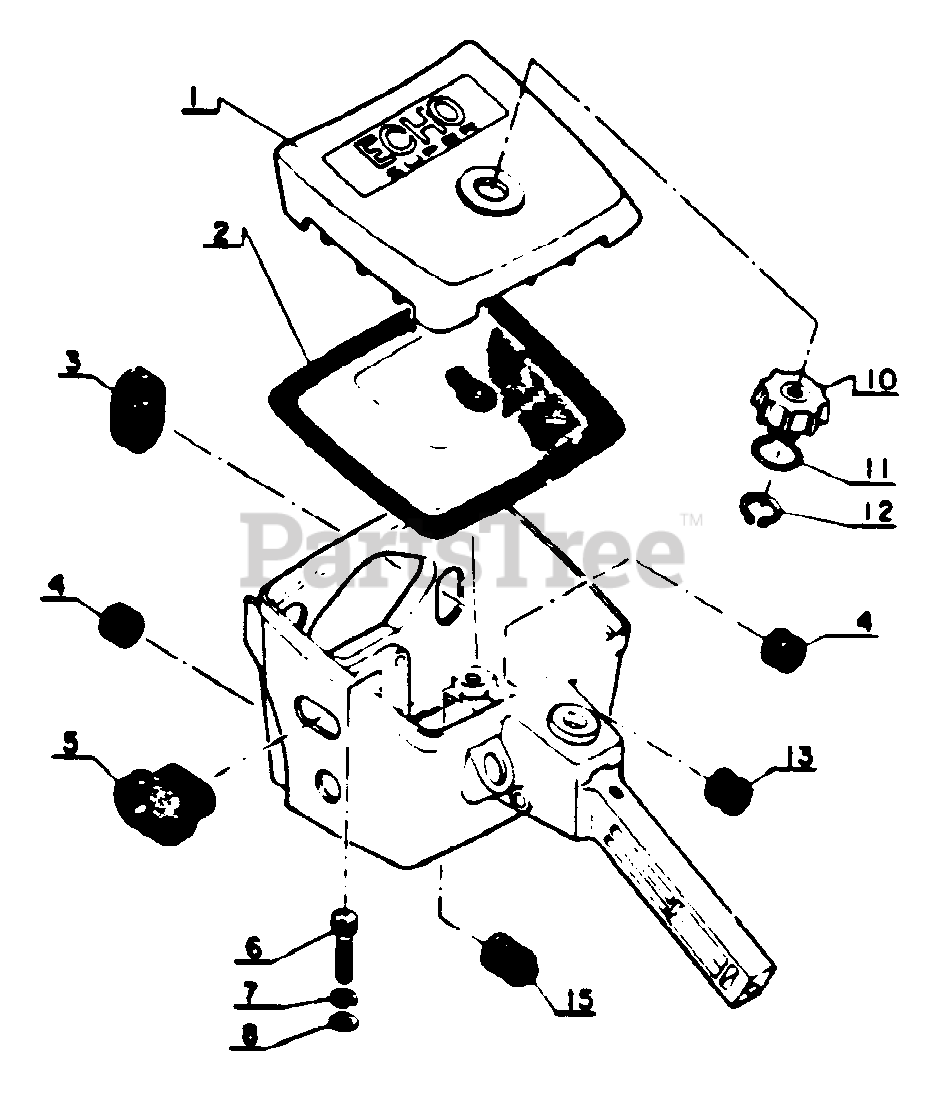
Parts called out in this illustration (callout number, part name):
1	COVER, AIR FILTER
2	FILTER, AIR
5	GROMMET
6	SCREW - 5X20
6	BOLT - 5X20
7	LOCKWASHER - 5
8	WASHER - 5
9	ECHO, name plate
10	WINGNUT
11	O-RING
12	RING, RETAINING - 11
16	SEAL, DUST
